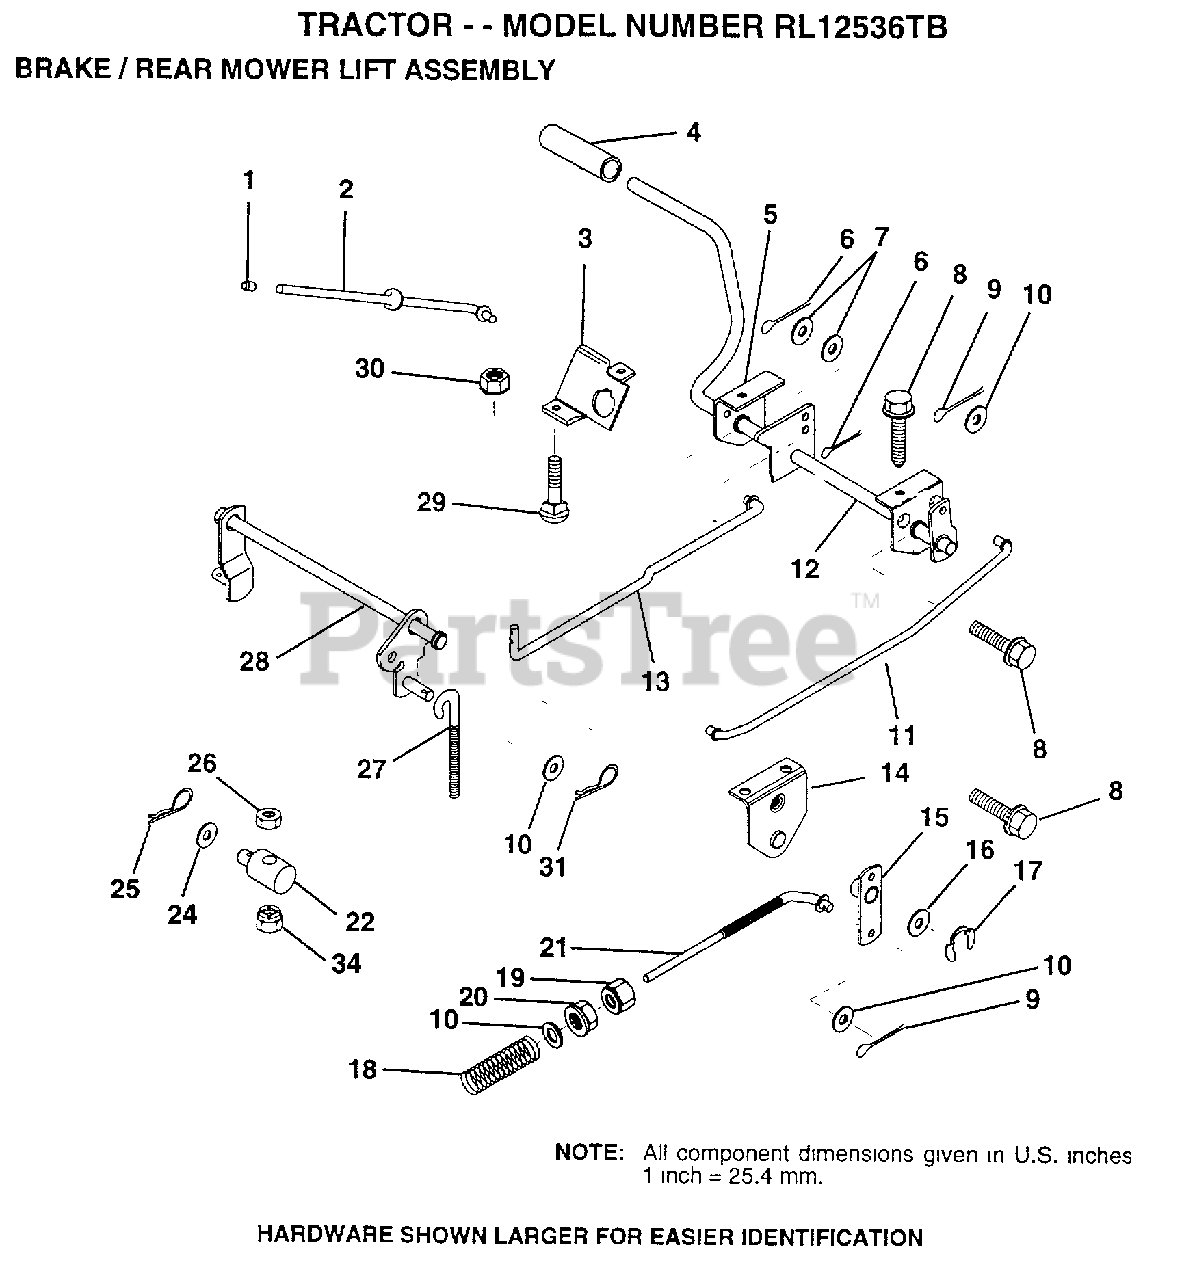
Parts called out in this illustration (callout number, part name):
1	PLUNGER CAP T
2	"ROD,PARK BRAKE"
3	"BRKT,PARK BRAKE"
4	FOOT PEDAL COVER
5	"BRKT,CLU PEDAL LH"
7	WASHER
8	SCREW LT
9	COTTER PIN
10	WASHER
11	"ROD,FRT BRAKE"
12	PEDAL ASM CL/BK36
13	"ROD,CLUTCH"
14	"BRKT,LIFT SHAFT"
15	PVT BRAKE ARM ASM
16	WASHER T
17	KLIP RING
18	SPRING ROD BRAKE
19	NUT
20	NUT
22	TRUNNION.LIFT.
24	WASHER
25	SPRING.RETAINER
26	LOCKNUT
27	"LINK, MOWER REAR"
28	LIFT ASM MOW REAR
31	RETAINER.SPRING
